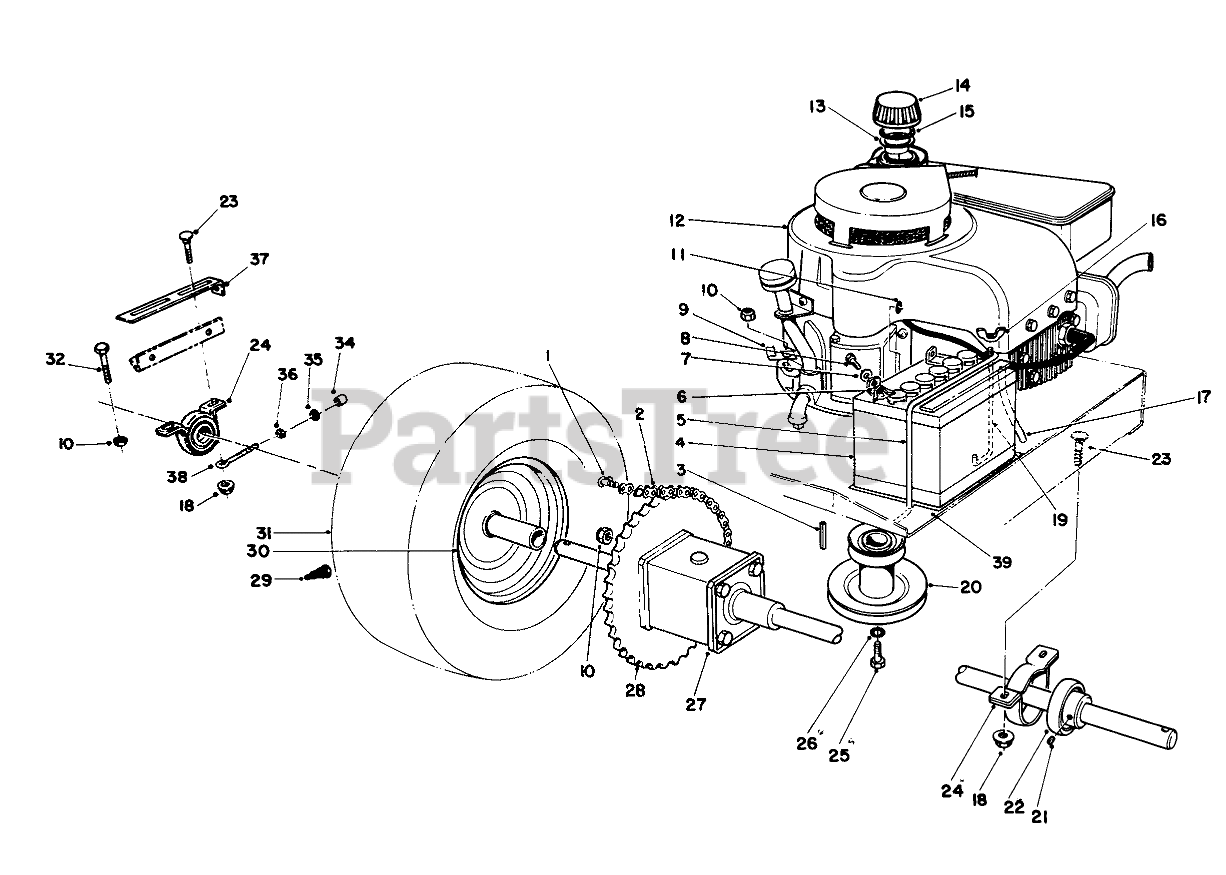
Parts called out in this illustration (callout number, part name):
1	LINK-CONNECTING
2	Chain-Roller (Incl. Ref. #1)
4	Battery
5	BATTERY HOLDOWN
6	NUT-WING
7	WASHER-FLAT
8	SCREW-HH
9	CLAMP
10	NUT-LOCK, NI
11	WASHER-LOCK/EXT
13	GAS CAP BAFFLE
14	Gas Cap Assembly (Incl. Ref. #13, 15)
15	GASKET
16	NUT-WING SPECL
17	TUBE-BATT DRAIN/80-2600
18	NUT-HF
19	POST-BATTERY
20	ENGINE PULLEY BO
21	SCREW-HSH
22	Bearing (Incl. Ref. #21)
23	SCREW-CARR
24	RTNR-PILLOW BLK
25	SCREW-HH
26	WASHER-LOCK
27	DIFFERENTIAL
28	45 T SPROCKET
29	STEM-VALVE
30	WHEEL-REAR
31	TIRE,PNEU.13X5.00X6
32	Bolt
33	BOLT-CARR
34	VINYL ROD TIP
35	NUT-HEX
36	NUT-HF
37	PLATE-ADJUSTING
38	SCREW-ADJUSTING
39	PAD-SKID, ANTI
